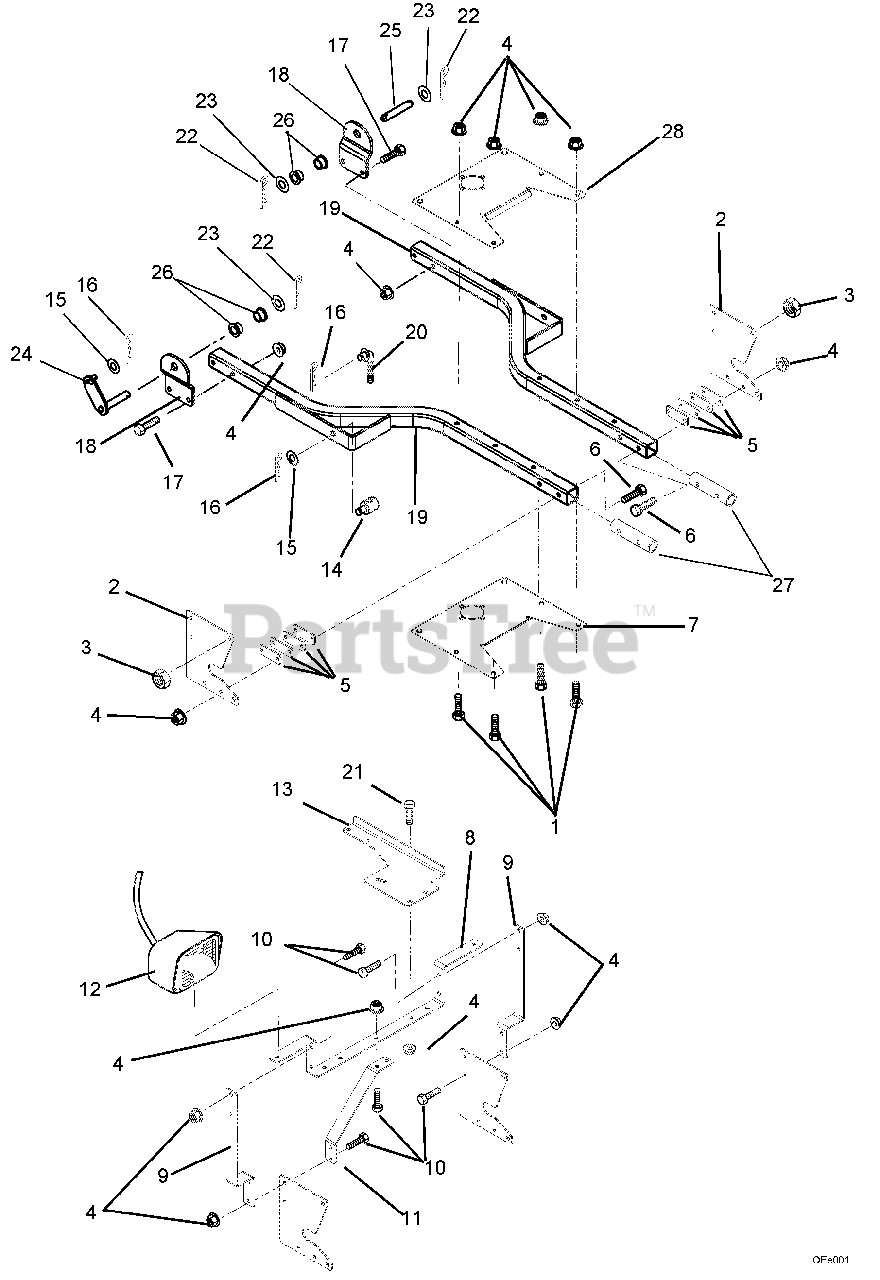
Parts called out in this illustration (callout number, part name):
1	Hex Bolt, .38-16 x 2.50 Grade 5
2	Plate, Sno-Thro Mount
3	Nut, Locking, Center .50-13
4	Nut, Locking, Top, Flange .38-16
5	Plate, Shim
6	Bolt, Hex .38-16 x 3.00 Grade 5
7	Plate, Subframe
8	Light-Bar, Snow Throw
9	Support, Light-Bar, Snow Throw
10	Bolt, Hex .38-16 x 1.00 Grade 5
11	Gusset, Light-Bar
12	Headlight
13	Bracket, Deflector Control
14	Trunnion
15	Washer, Flat Steel .531 x 1.250 x .100
16	External Hair Pin - #16 Black Zinc
17	Hex Bolt, .38-16 x 2.5 Grade 5
18	Pivot Bracket
19	Weldment, Sub-Frame Tube
20	Lift Link
21	Bolt, Round Head Square Neck .38-16 x 1.00 Grade 5
22	Pin, Hair Int. .15 x 2.937
23	Washer, Flat Steel .812 x 1.50 x .135
24	Pin, Right Rear Lift Pivot
25	Pin, Left Rear Lift Pivot
26	Bushing, .75 x 1.00 x .625 x 1.25 Flange
27	Tube, Anti-Crush
28	Plate, Subframe Top
